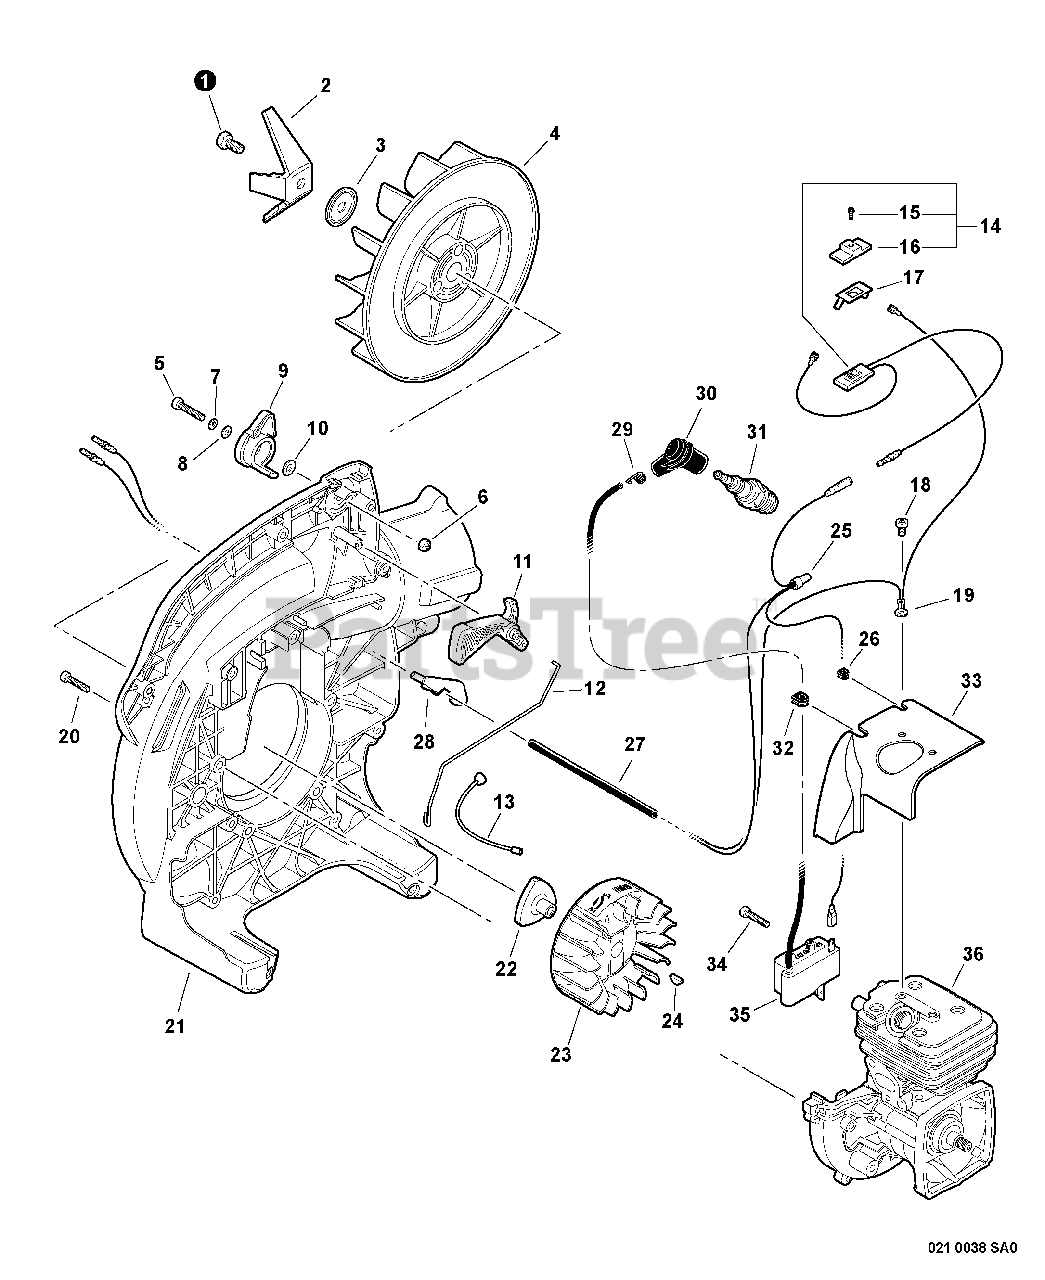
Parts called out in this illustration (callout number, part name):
1	BOLT 8×15
2	CUTTER, SHREDDER
3	WASHER 8.2×31×0.8
5	BOLT, TORX 5×25
6	NUT, LOCK M5
7	WASHER, SPRING 5
8	WASHER 5.5×12×0.8
9	CONTROL, THROTTLE
10	WASHER 5.5×12×0.8
11	TRIGGER, THROTTLE
12	ROD, THROTTLE
13	CABLE, THROTTLE
14	SWITCH ASSY, ON-OFF
15	SCREW 3×10
16	KNOB, SWITCH
17	TERMINAL, LEAD
18	BOLT, TORX 5×8
20	BOLT, TORX 4×20
21	CASE, FAN
22	HUB, FAN
23	FLYWHEEL
24	KEY, WOODRUFF
27	TUBE, INSULATOR
29	TERMINAL, SPARK PLUG
30	CAP, SPARK PLUG
31	SPARK PLUG - BPM8Y
31	SPARK PLUG - BPMR8Y
33	SHIELD, CYLINDER
34	BOLT, TORX 4×20
35	COIL, IGNITION
36	SHORT BLOCK
